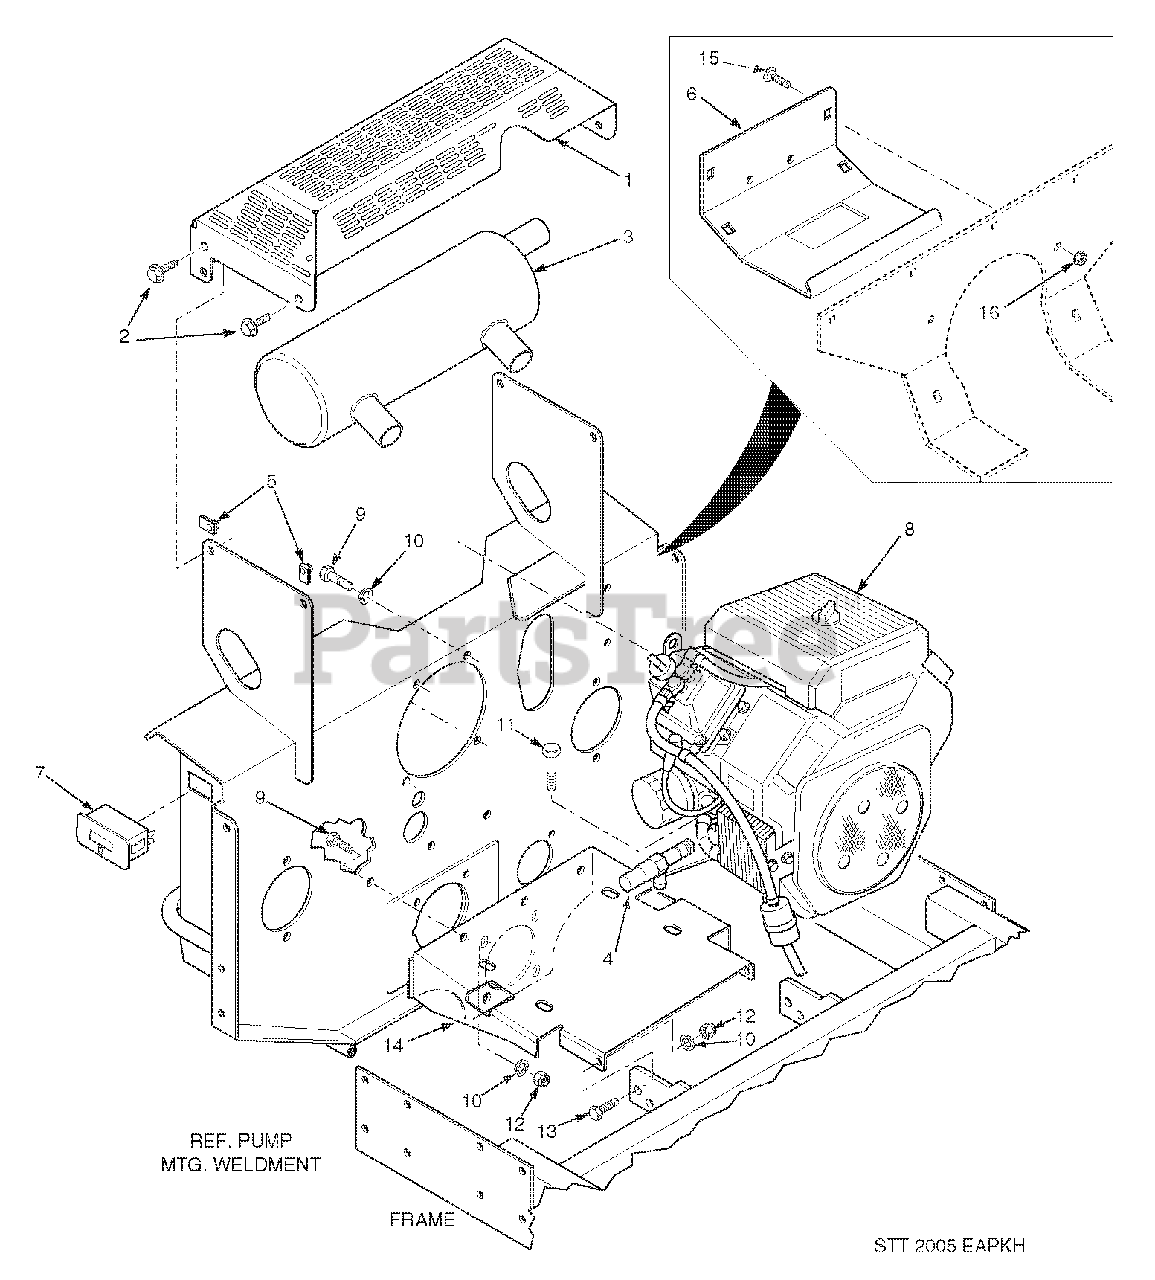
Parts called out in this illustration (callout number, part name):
1	Muffler Guard
2	Screw, Hex Serrated Flange 1/4-20 x 3/4"
3	Muffler, Part Of Engine
4	Oil Drain Extension
5	U-Nut, 1/4-20
6	Rear Cover
7	Hour Meter
8	Engine, Kohler 27 CH
9	Bolt, Hex Head 3/8-16 x 1"
10	Lockwasher, 3/8" Spring
11	Bolt, Hex Head 3/8-16 x 1-3/4"
12	Nut, Hex Elastic Stop 3/8-16
13	Bolt, Hex Head 3/8-16 x 1-1/4"
14	Plate, Engine Mounting
15	Bolt, Carriage 5/16-18 x 3/4"
16	Nut, Hex Serrated Flange 5/16-18
